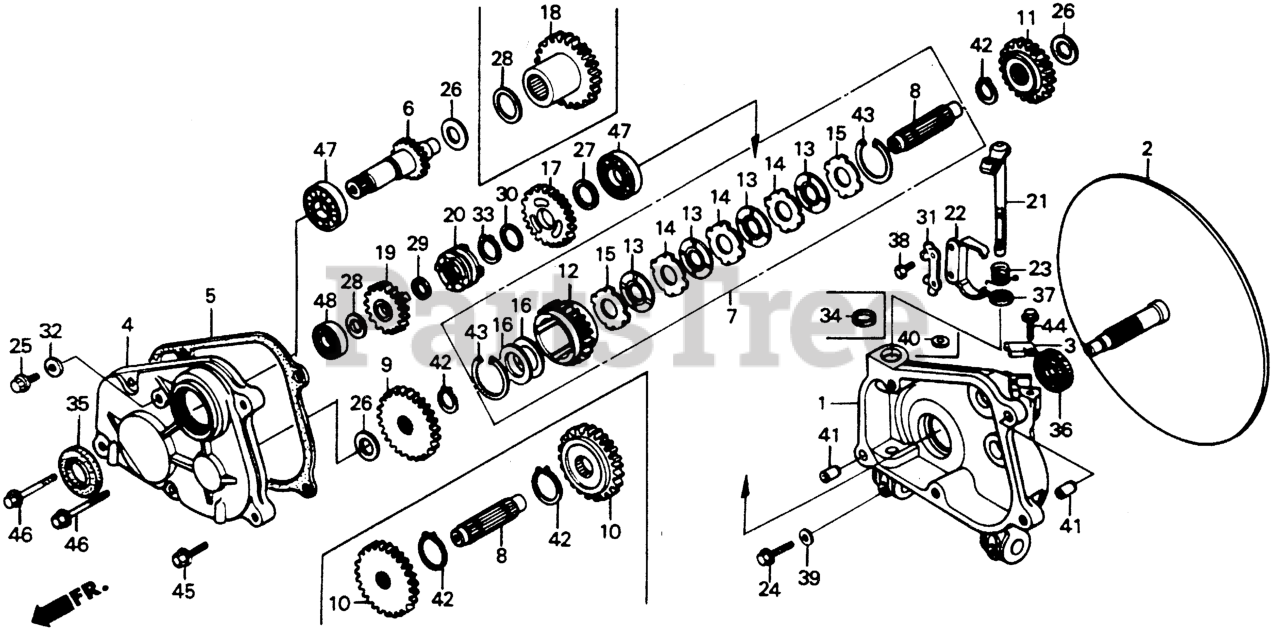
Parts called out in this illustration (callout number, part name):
1	CASE, SUB-TRANSMISSION
2	DISK, DRIVE
3	HOLDER, SUB-TRANSMISSION CABLE
4	COVER, SUB-TRANSMISSION
5	GASKET, SUB-TRANSMISSION (NOT AVAILABLE)
6	SHAFT, PRIMARY (NOT AVAILABLE)
7	CLUTCH ASSY.
8	COUNTERSHAFT
9	GEAR, COUNTERSHAFT FIRST (34T)
11	GEAR, COUNTERSHAFT SECOND (27T)
12	CLUTCH (OUTER) (NOT AVAILABLE)
13	DISK, CLUTCH FRICTION (NOT AVAILABLE)
14	PLATE A, CLUTCH
15	PLATE B, CLUTCH
16	SPRING, DISK (NOT AVAILABLE)
17	GEAR, FINAL SECOND
19	GEAR, FINAL FIRST (23T)
20	SHIFTER (NOT AVAILABLE)
21	SHAFT, SHIFT FORK
22	FORK, SHIFT
23	SPRING, LEVER RETURN
24	BOLT, KNOCK (6MM)
25	BOLT, DRAIN PLUG
26	WASHER (14MM)
27	WASHER (17MM)
28	WASHER (10X21)
29	WASHER (13)
31	WASHER, TONGUED
32	WASHER, DRAIN PLUG (10.2MM)
33	CIRCLIP (OUTER) (17MM)
35	OIL SEAL (17X28X7)
36	OIL SEAL (20X32X7)
37	OIL SEAL (10X16X4.5)
38	BOLT, HEX. (5X10)
39	WASHER, PLAIN (6MM)
41	PIN A, DOWEL (8X14)
42	CIRCLIP (OUTER) (16MM)
43	CIRCLIP (INNER) (34MM)
44	BOLT, FLANGE (6X12) Use up to Engine SN 1543277.
45	BOLT, FLANGE (6X25)
46	BOLT, FLANGE (6X32)
47	BEARING, RADIAL BALL (6003)
48	BEARING, RADIAL BALL (6200)
